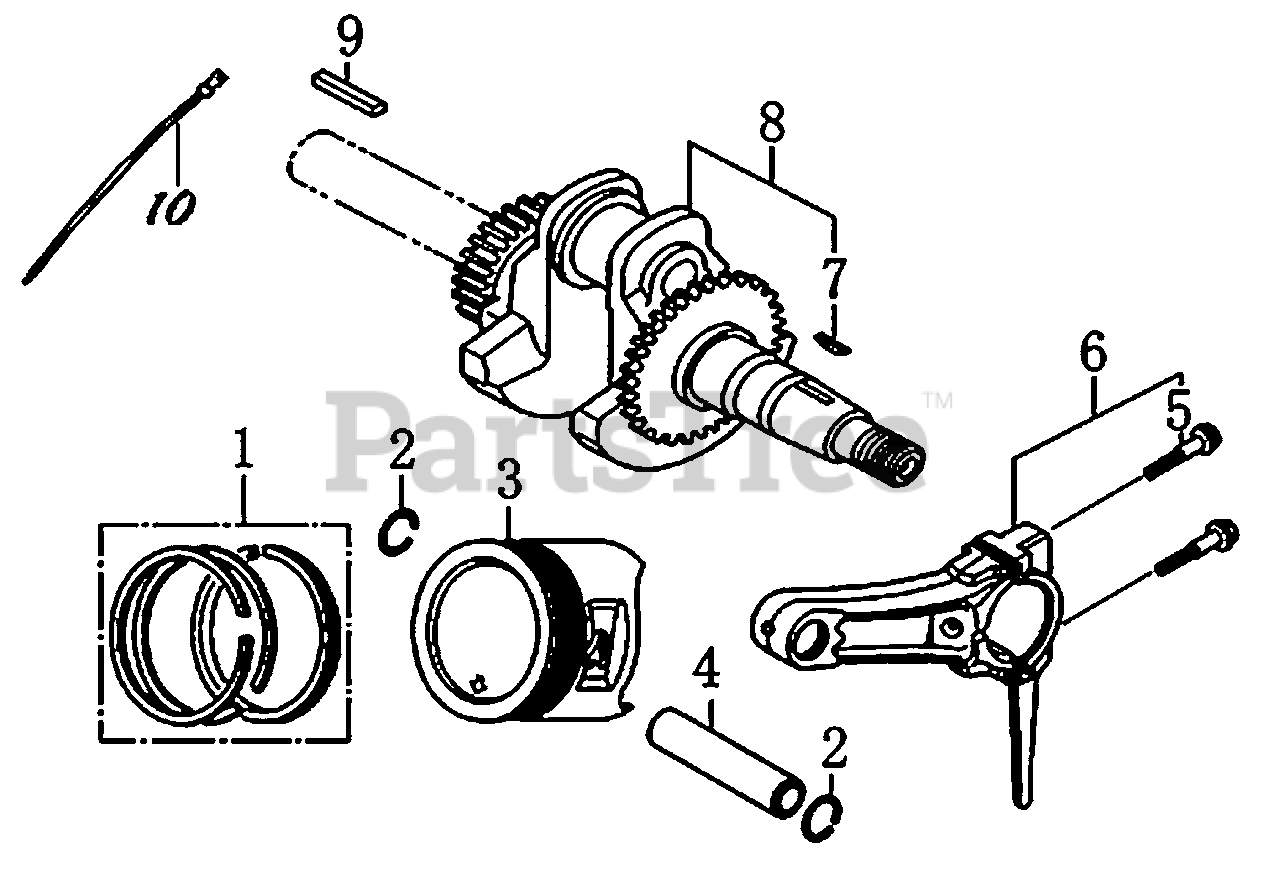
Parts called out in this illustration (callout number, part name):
2	CLIP, PISTON PIN
4	PIN, PISTON
5	BOLT, CONNECTING ROD
6	ROD ASSY., CONNECTING
8	CRANKSHAFT COMP
10	TIE WRAP
